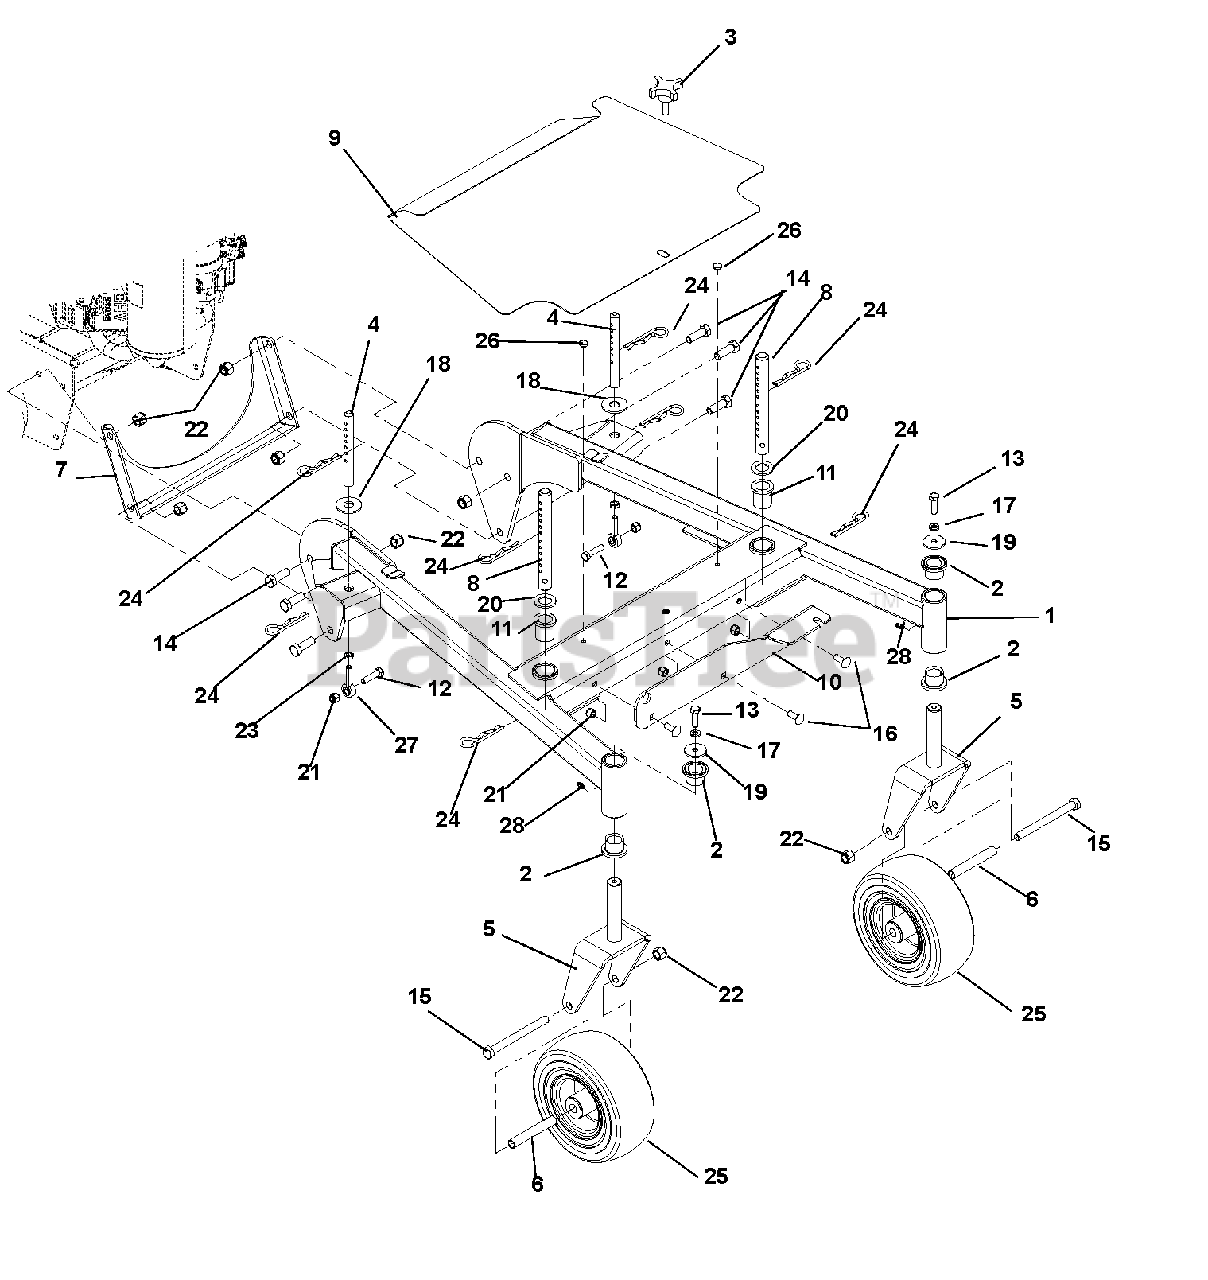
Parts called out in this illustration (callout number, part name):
1	Frame, Pro-Gear Carrier
2	Bearing, Flange 1.00 x 1.25 x 1.00
3	Knob, .38 x 1.25- 4-Prong (SN 000101 – 019999)
4	Rod, Rear HOC
5	Weldment, Front Wheel
6	Tube, Caster Axle
7	Bracket, Engine Crossplate
8	Pin, HOC
9	Shield, Carrier Frame (SN 000101 – 020999)
10	Bracket, Chute Storage
11	Bushing, Flange 1.00 x 1.25 x 1.50 x 1.50
12	Bolt, Hex .38-16 x 1.50 Grade 5
13	Bolt, Hex .38-16 x 1.25 Grade 5
14	Bolt, Hex .50-13 x 1.50 Grade 5
15	Bolt, Hex .50-13 x 5.50 Grade 5
16	Bolt, Round Head Square Neck .38-16 x 1.00 G5
17	Washer, Locking .38 x .094 Regular
18	Washer, Flat-Steel .688 x 1.75 x .134
19	Washer, Flat-Steel .380 x 1.50 x .125
20	Washer, Flat-Steel .875 x 1.500 x .1196
21	Nut, Locking-Nylon .38-16
22	Nut, Locking-Nylon .50-13
23	Nut, Jam .375-24
24	Pin, Hair-Internal .17 x .68 x 3.50
25	Assembly, Wheel and Tire 9 x 3.5 (SN 000101 – 010000)
26	Bumper Grommet .125 x .250 Diameter
27	Rod End, .38 Right Hand
28	Fitting, 1/4-28 STRGT Grease Zerk
